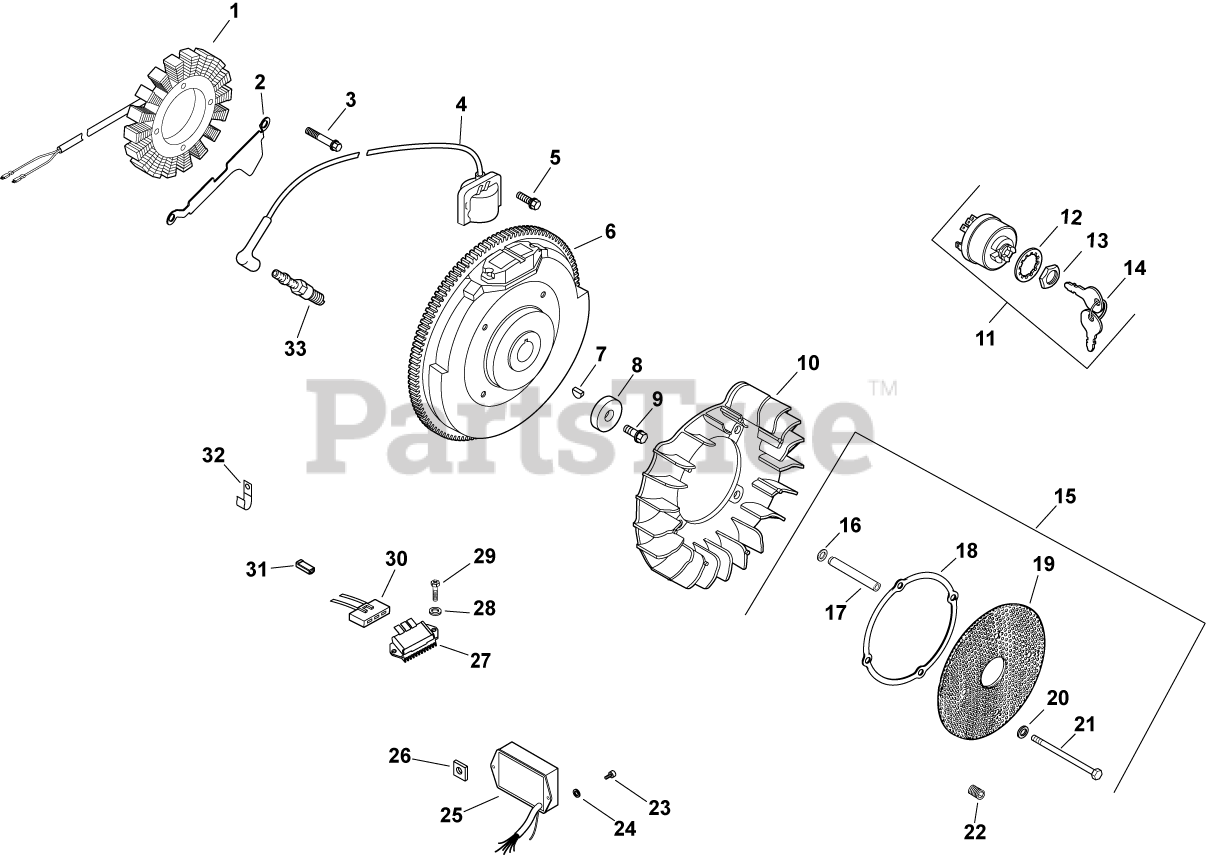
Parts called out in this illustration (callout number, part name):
1	KIT, 15 / 20 AMP STATOR
2	BRACKET, STATOR WIRE
3	SCREW, M5X0.8X25 - (#25086402S)
4	MODULE, IGNITION
5	SCREW, FLG THD FRM M5X.8X20-(#25086399S)
6	FLYWHEEL, PAINTED-USE 24 025 57-S
7	KEY, 3/16" X 5/8"
8	WASHER, FLAT 13/32"
9	SCREW, FLG M10X1.5X45 - (#25086361S)
10	FAN (WITH HOLE)-USE 24 157 16-S
11	SWITCH ASSY, KEY (KM)-USE 25 099 32-S
12	WASHER, INTERNAL TOOTH
13	NUT, KEY SWITCH
14	KEY, SET -USE 48 340 01-S
15	KIT, CHOPPER SCREEN
16	WASHER, SPRING 10 MM
18	RING, SUPPORT USE 25 141 08-S
19	SCREEN, GRASS
20	WASHER, FLAT 1/4" (O.D. 5/8")
21	SCREW, SOCKET TRUSS HD CAP
22	SCREW, SKT SET #10-24X1/4"
23	SCREW, PHL HD #11-16X1/2"
24	WASHER, FLAT 1/4" (O.D. 1/2")
25	MODULE, SPEED ADVANCE-DISCONTINUED SEE PB265
26	NUT, PLASTIC
27	REG/RECTIFIER (20/25 AMP)-USE 25 403 20-
28	WASHER, FLAT 3/16"
29	SCREW, PHL HD #11-16X7/8"
30	CONNECTOR, BODY (KM)-USE 25 155 41-S
31	CONNECTOR (1 CONTACT)
32	CLIP, CABLE
33	PLUG, SPARK (PRO SERIES)
